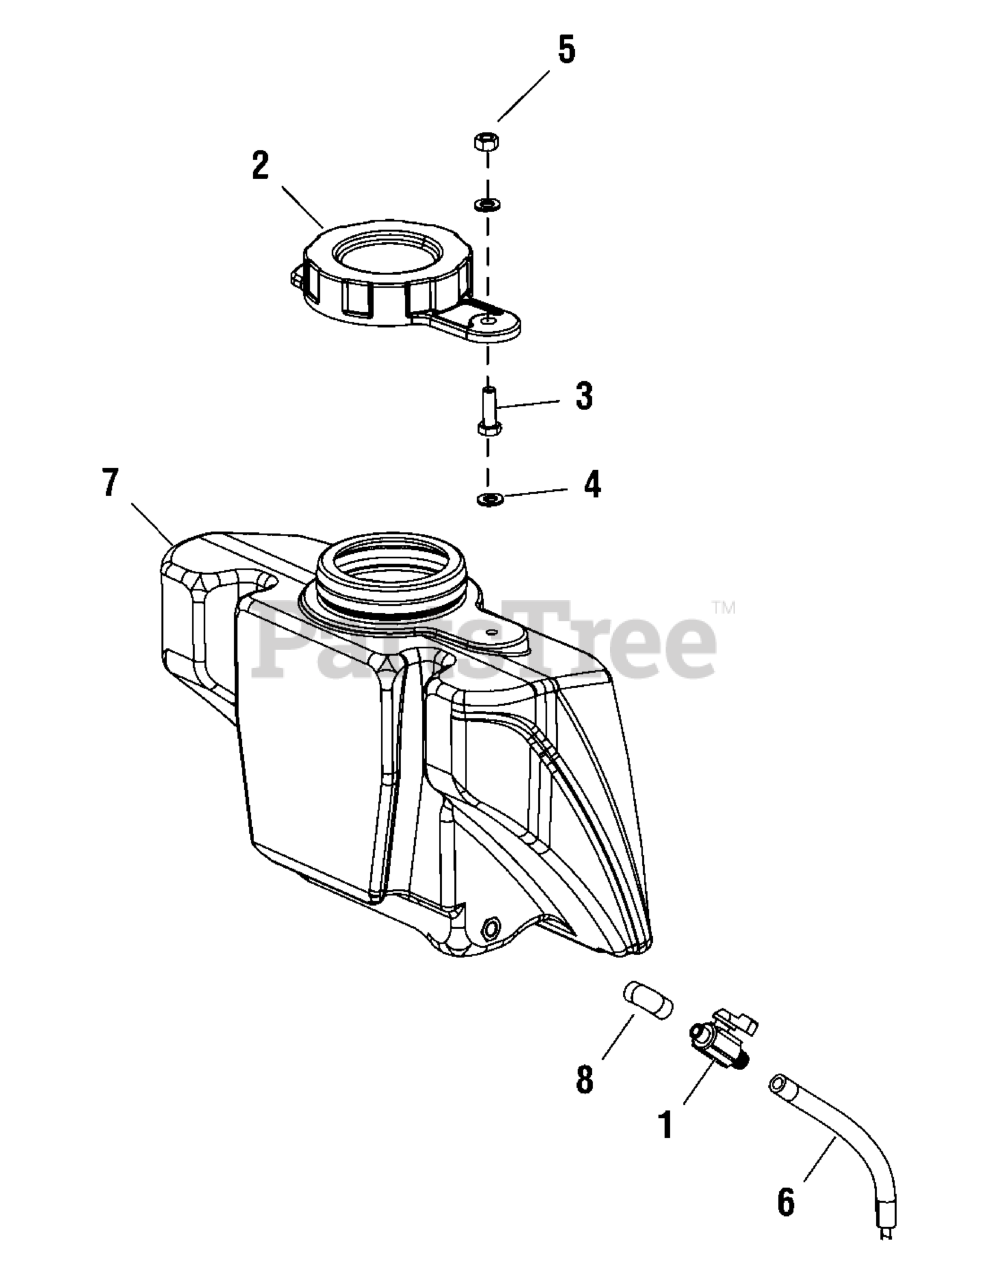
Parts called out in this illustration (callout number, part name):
1	VALVE, Brass Ball
2	COVER, Water Tank
3	BOLT, Hex, M10 x 30
4	WASHER, Flat
5	NUT, Nex, M10
6	WATER PIPE, Rubber
7	WATER TANK
8	CONNECTOR, L-Type
